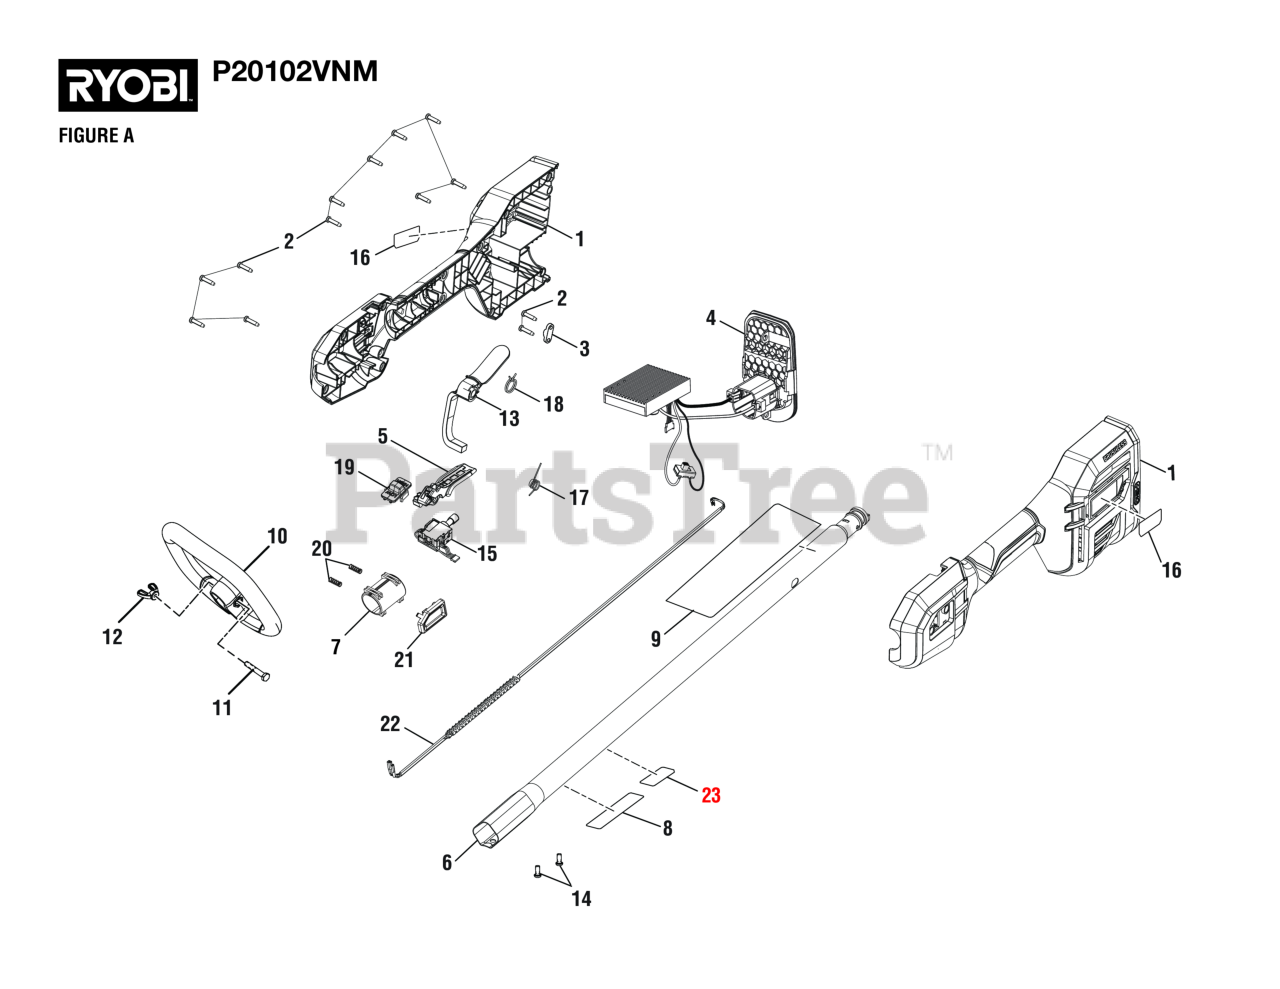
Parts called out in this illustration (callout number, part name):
1	Rear Handle Assembly
2	Screw (M4 x 14 mm, T15 Torx Pan Hd.))
3	Wire Press Plate
4	Motor Controller and Switch Assembly
6	Upper Boom Assembly
7	Boom Holder
8	Data Label
9	Warning Icons Label
10	Auxiliary Handle Assembly
11	Screw (1/4-20 x 40 mm, Cap Hex Hd.)
12	Wing Nut (1/4-20, Plastic)
13	Lock-Out Trigger
14	Screw w/Lock Washer (M5 x 8 mm, Pan Hd.)
15	Switch, Variabel Speed, 12VDC
16	Logo Label
17	Screw w/Lock Washer (M5 x 8 mm, Pan Hd.)
18	Torsion Spring
19	Slide Switch Cover
21	Rotation Button
22	Spring Wire
